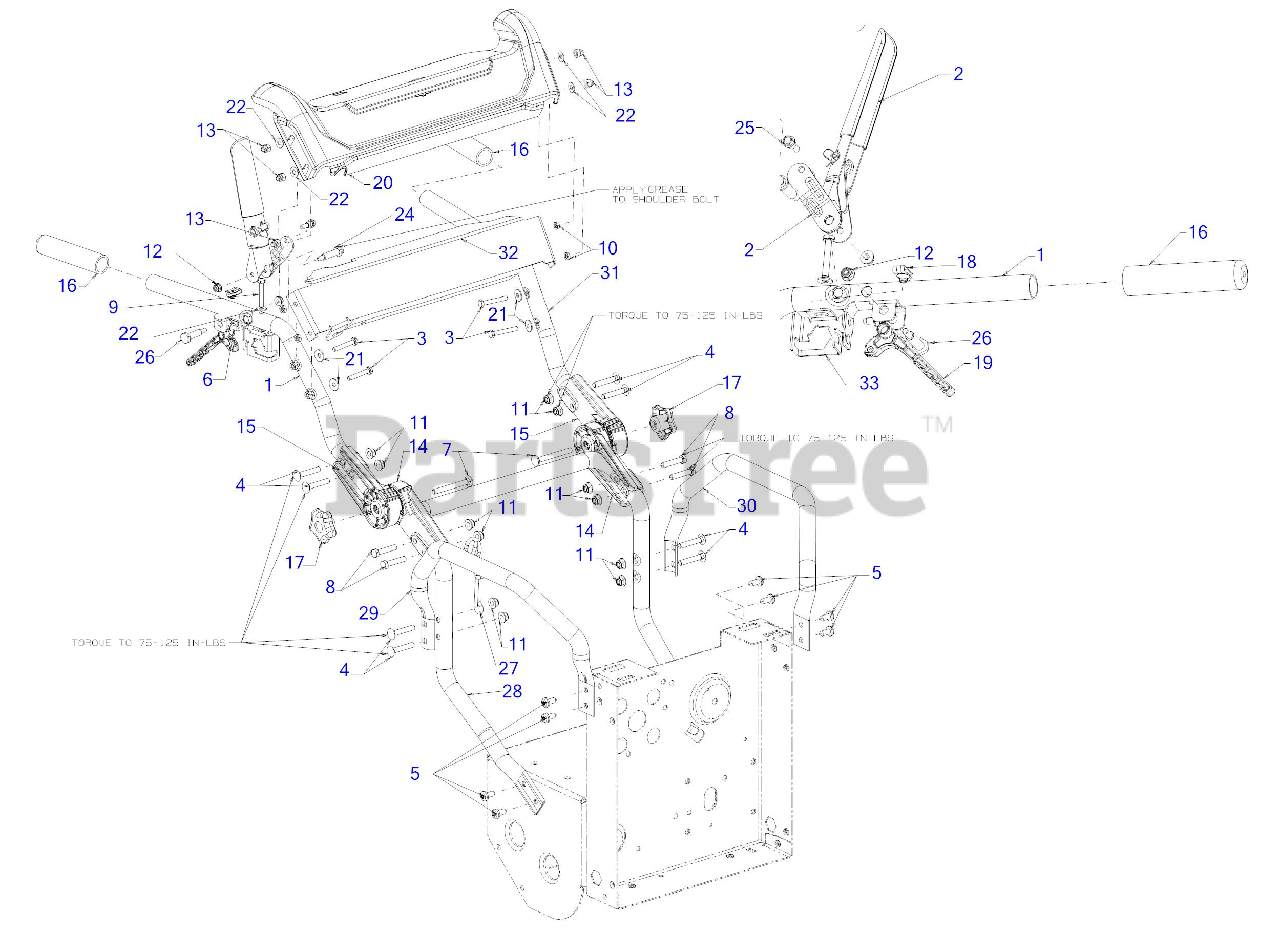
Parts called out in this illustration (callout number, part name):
1	UPPER HANDLE ASSEMBLY (RH)
2	LEVER LOCK ASSEMBLY
3	HEX SCREW 1/4-20 x 1.75
4	CARRIAGE BOLT 5/16-18 x 1.75
5	SCREW 5/16-18 x .750
6	SCREW 1/4-20 X.500
7	CARRIAGE BOLT 5/16-18 x 2.75 GR5
8	SCREW 5/16-18 x 1.5 LG
9	BOLT 1/4-20X1.62 GR5
11	FLANGE LOCK NUT 5/16-18
12	FLANGE LOCK NUT
13	HEX ACORN NUT
14	LOWER ADJUST HANDLE
15	HANDLE-UPPER ADJUST
17	STAR KNOB- RED
18	U-CLIP NUT
19	DRIVE CABLE LEVER
20	HANDLE COVER
21	SPRING WASHER BELL
22	FLAT WASHER
24	SHOULDER BOLT .375X1.285:1/4-20
25	SHOULDER SCREW .342X.335X1/4-20
26	SHOULDER SCREW
27	ROPE GUIDE ROD
29	CART FRAME TUBE (RH)
30	CART FRAME TUBE (LH)
31	UPPER HANDLE (LH)
33	CABLE BRACKET
